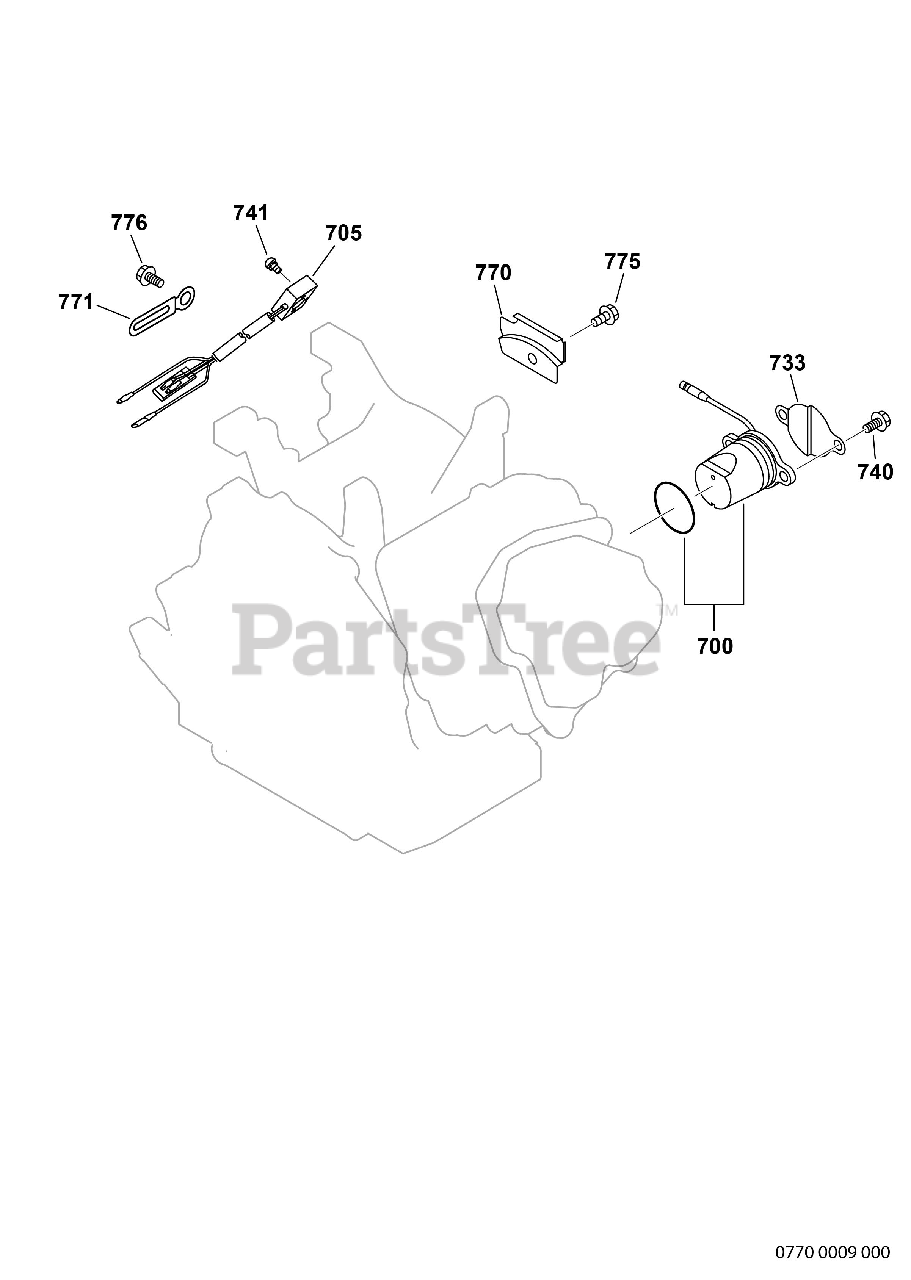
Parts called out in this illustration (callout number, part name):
705	FLOAT C/U CP11
741	SCREW AND WASHER AY
773	SHIELD PLATE (O/S)
